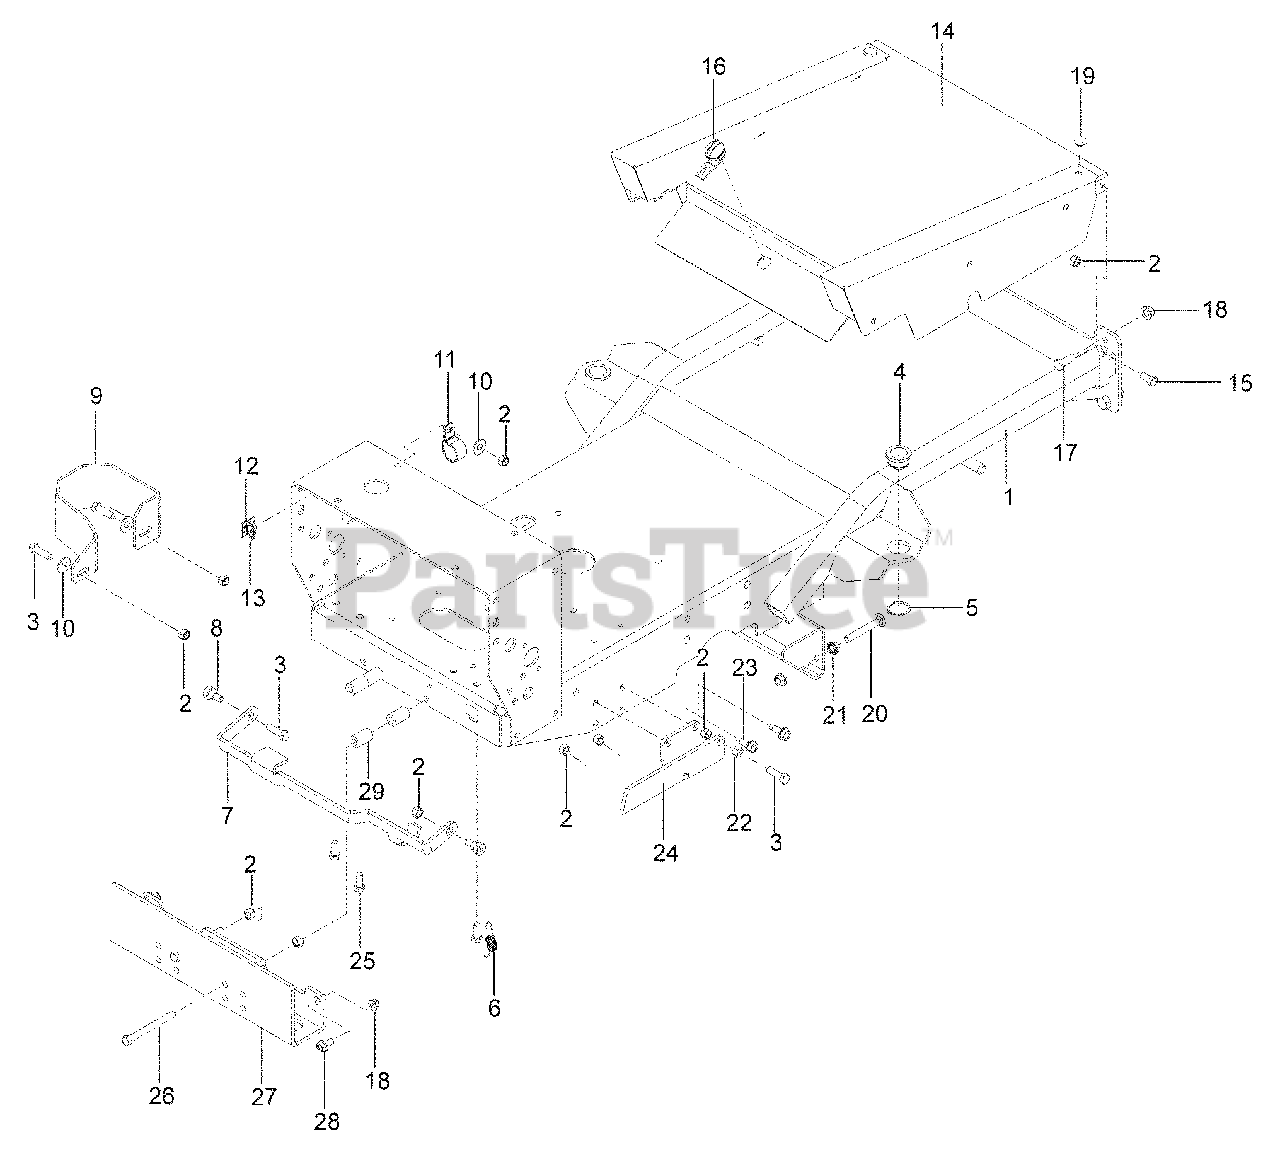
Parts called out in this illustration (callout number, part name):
2	NUT 3/8-16 HEX NYLOC
3	HCS 3/8-16 x 1¼
4	BUSHING, HOC
5	RING, SNAP
6	SPRING, EXTENSION
7	BAR, THROW OUT
8	SB 3/8-16 x 3/8 SKT HD
9	GUARD, FILTER
10	WASHER 3/8 FLAT
12	MOUNTING BLOCK
14	COVER, CENTER
15	HCS 3/8-16 x ¾
16	LATCH, SHORT WING
17	HCS ½-13 x 1¼
18	NUT ½ HEX FLG NYLOC
20	RHSNB 3/8-16 x 2¾
21	NUT 3/8-16 HEX WHIZLK
22	NUT 3/8-16 HEX
23	BOLT 3/8-16 x 1 THD FRM
24	PLATE, SUPPORT
25	Hcs 3/8-16 x 7/8
26	HCS 3/8-16 x 3¾
28	HFFS ½-13 x 1
